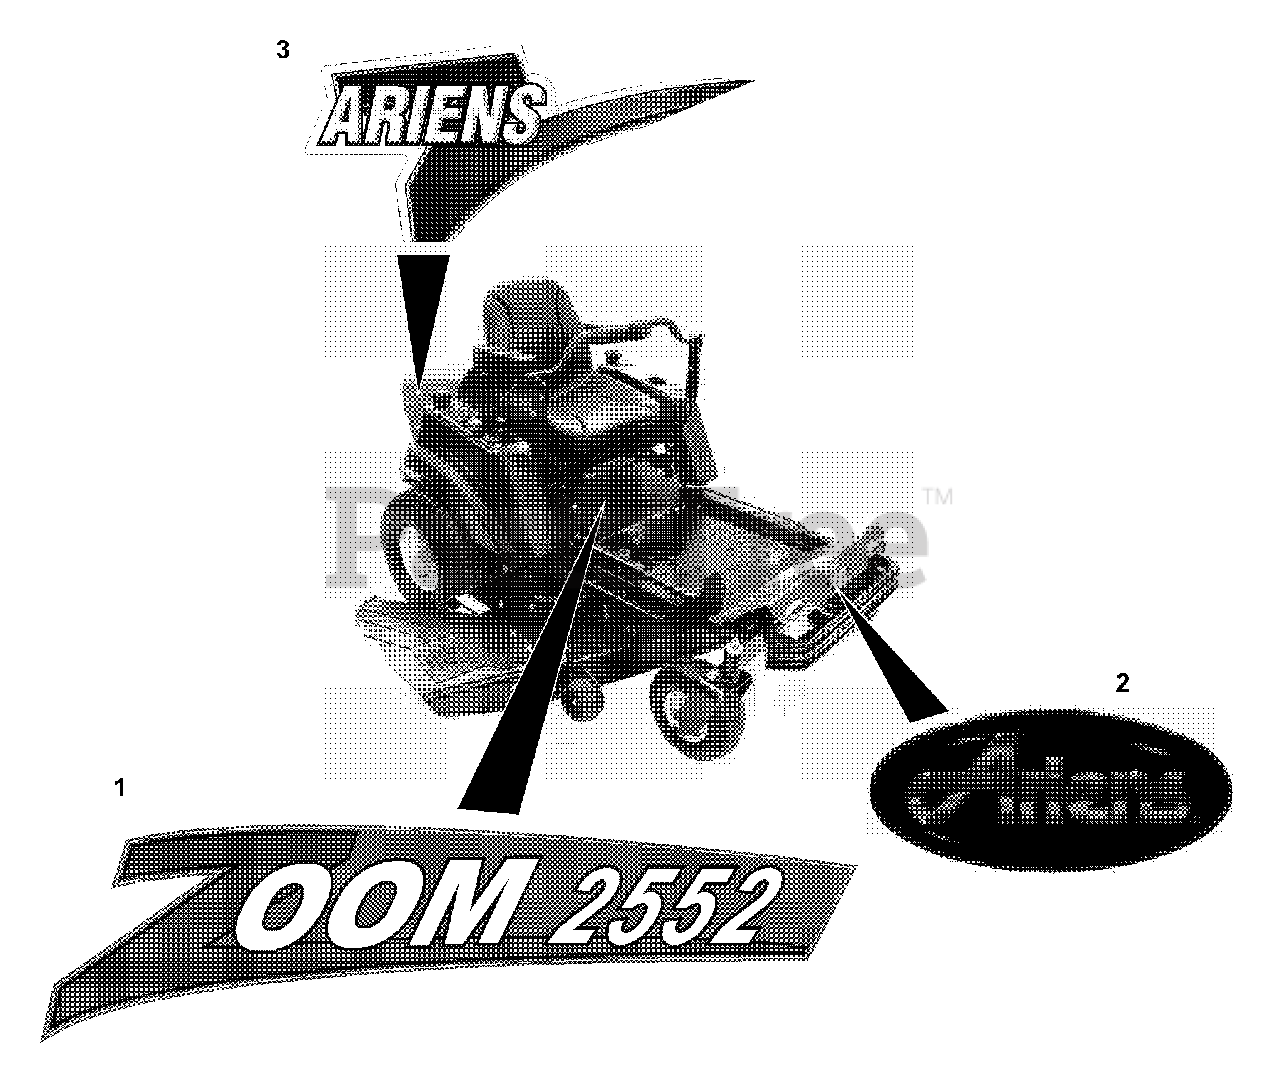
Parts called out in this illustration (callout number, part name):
1	DECAL, ZOOM 1640
2	DECAL-ARIENS JEWEL
3	DECAL, ZOOM HOOD
